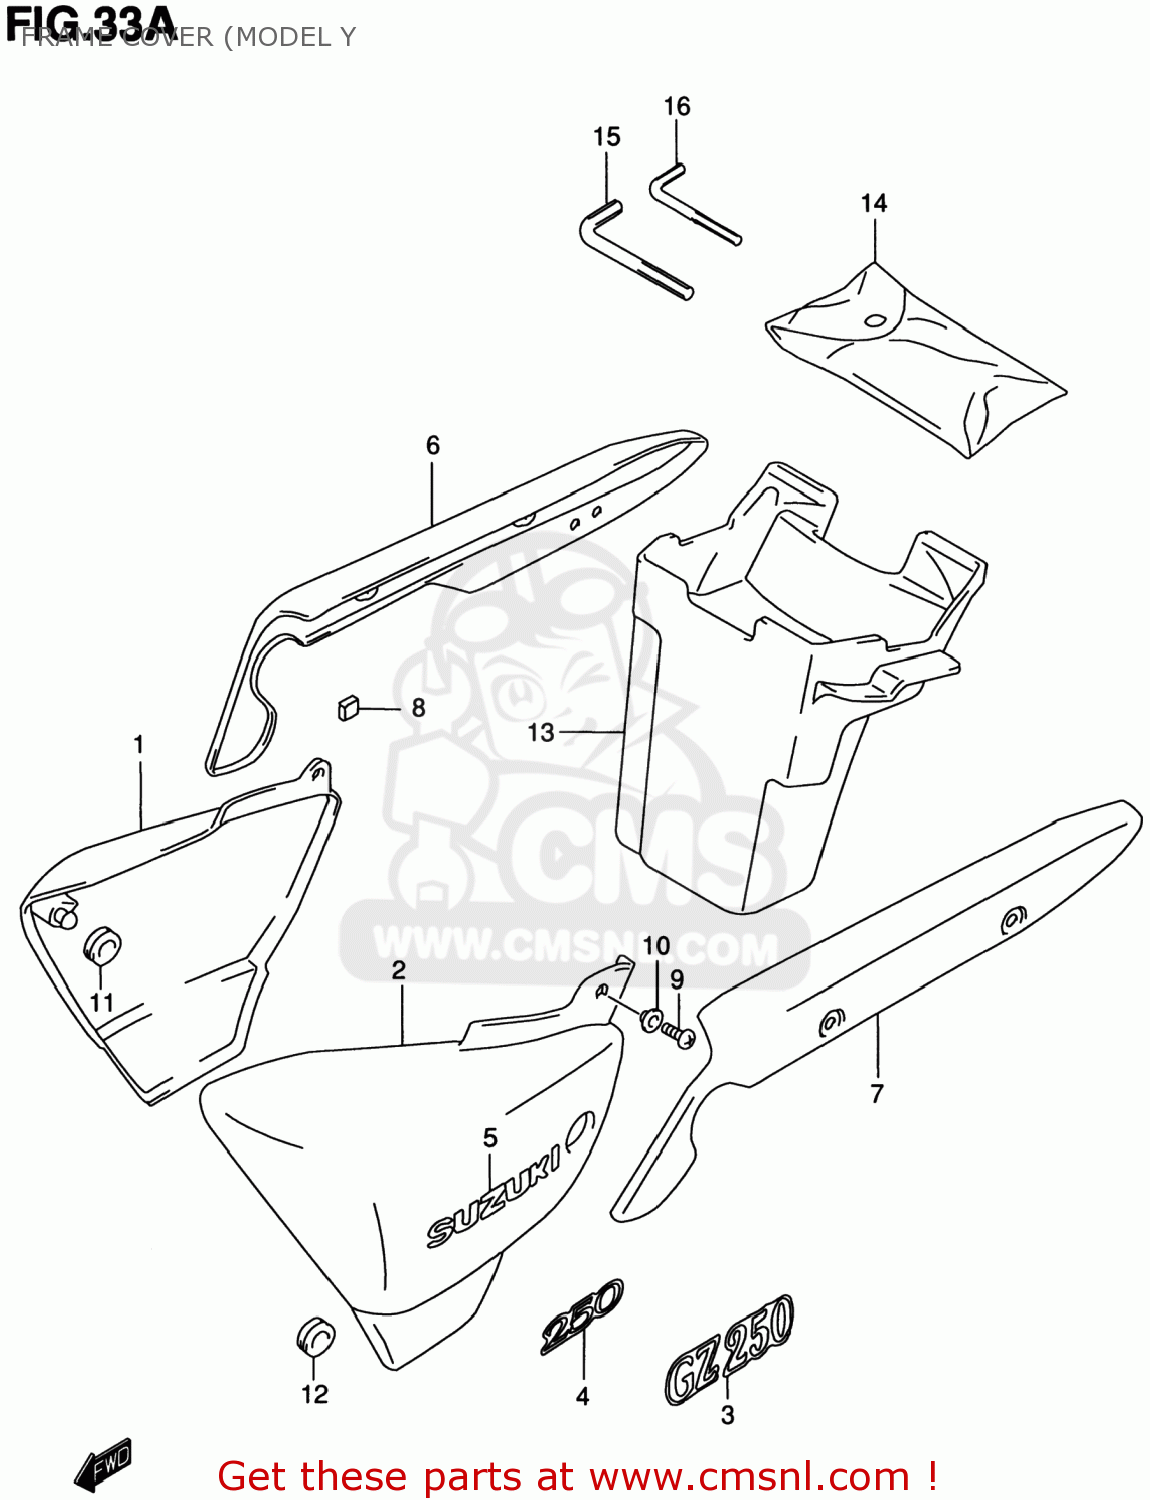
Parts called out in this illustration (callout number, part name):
1	COVER,FRAME,R(GREEN)
2	COVER,FRAME,L(GREEN)
3	EMBLEM,FRAME COVER
4	EMBLEM,250
5	EMBLEM,FRAME COVER
6	COVER,FRAME RR,R
7	COVER,FRAME RR,L
8	CUSHION
9	SCREW 6X12
10	WASHER
11	CUSHION
12	CUSHION
13	BODY,LUGGAGE BOX
14	TOOL ASSY
15	SPANNER,HEXAGON(6)
16	SPANNER,HEXAGON(4)
